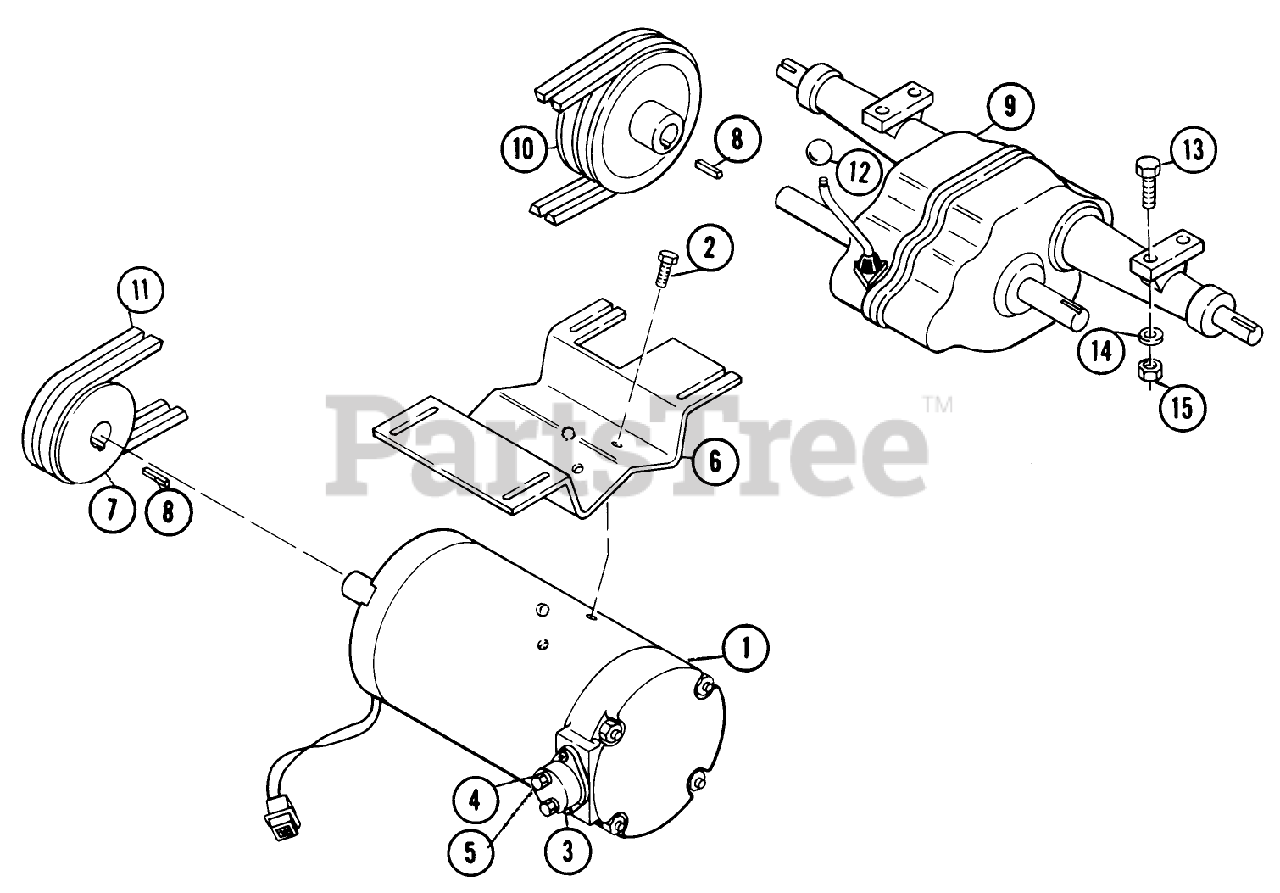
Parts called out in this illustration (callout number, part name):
9-06	Mounting Plate, Motor
9-09	ORDER COMPONENT PARTS
9-10	Pulley, Transmission
9-14	Spring Lockwasher
